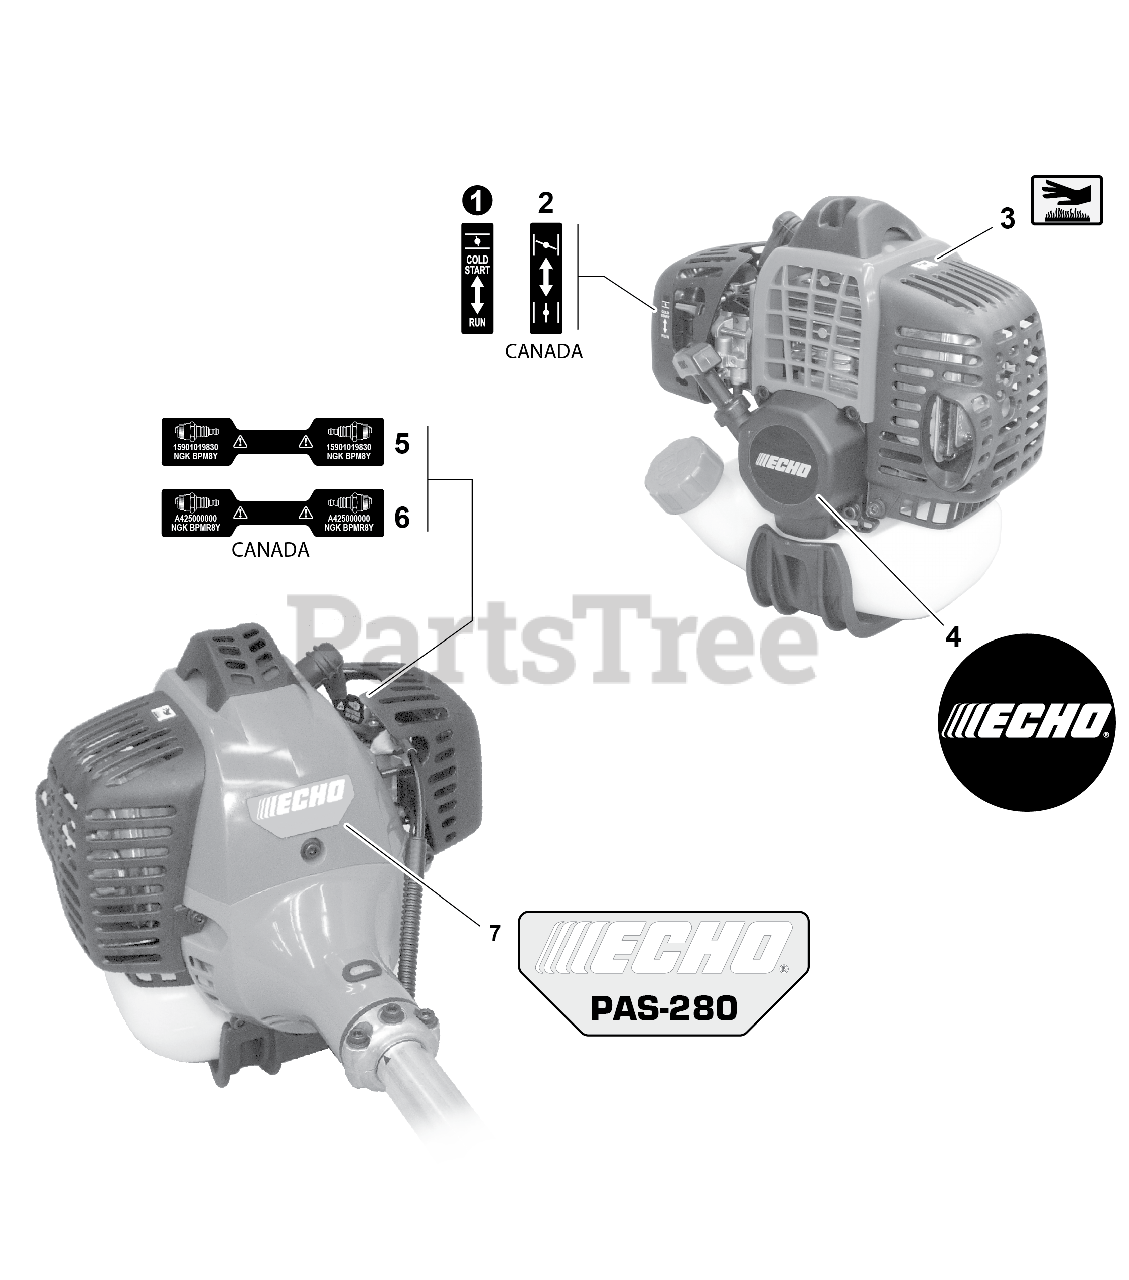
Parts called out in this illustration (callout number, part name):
1	LABEL - CHOKE
2	LABEL - CHOKE
3	LABEL - CAUTION -- HOT
4	LABEL - ECHO
5	LABEL - SPARK PLUG -- BPM-8Y
6	LABEL - SPARK PLUG -- BPMR-8Y
7	LABEL - MODEL -- PAS-280
